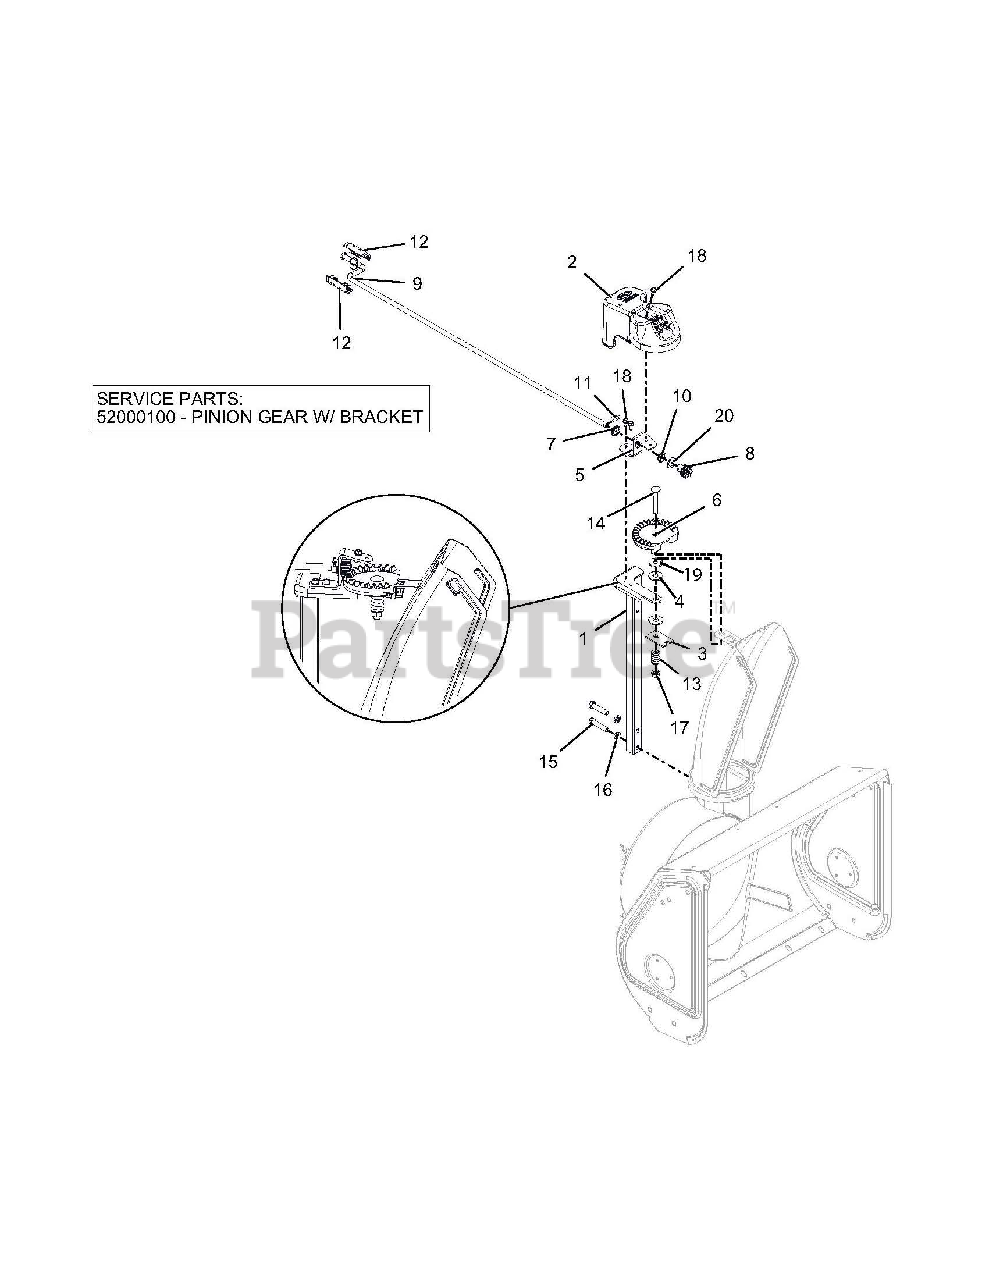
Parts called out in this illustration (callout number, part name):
1	CHUTE PEDESTAL, TALL COMPACT
2	GEAR COVER ASSY SM SHEAR BOLT
3	PLATE, FRICTION
4	FRICTION WASHER
5	BRACKET, PINION GEAR
6	CHUTE GEAR
7	PUSHNUT .625
8	PINION GEAR - CHUTE
9	ROD, CHUTE CRANK, COMP&SNOTEK
10	BUSHING, POLYLINER-.63 SNAPIN
11	PIN, SPRING CLIP
12	KNOB, CHUTE CRANK - SNAP GRAY
13	SG-COMP .187X.56X1.62
14	@BLT-RDHDSQNK .38-16X2.50 G5YZ
15	@BLT-HEX .38-16X1.75 GR5 YWZC
16	@WSHR-LK .38X.094 REG YWZC
17	@NUT-LK-TOP-FLG .38-16 YWZC
18	SCR-TAP .25-20X.50 HWH TR YWZ
19	@WSHR-FL-STL .406X1.25X.10 ZC
20	WSHR-THRST .625 X 1.0 X .03
21	PINION GEAR W/BRACKET
